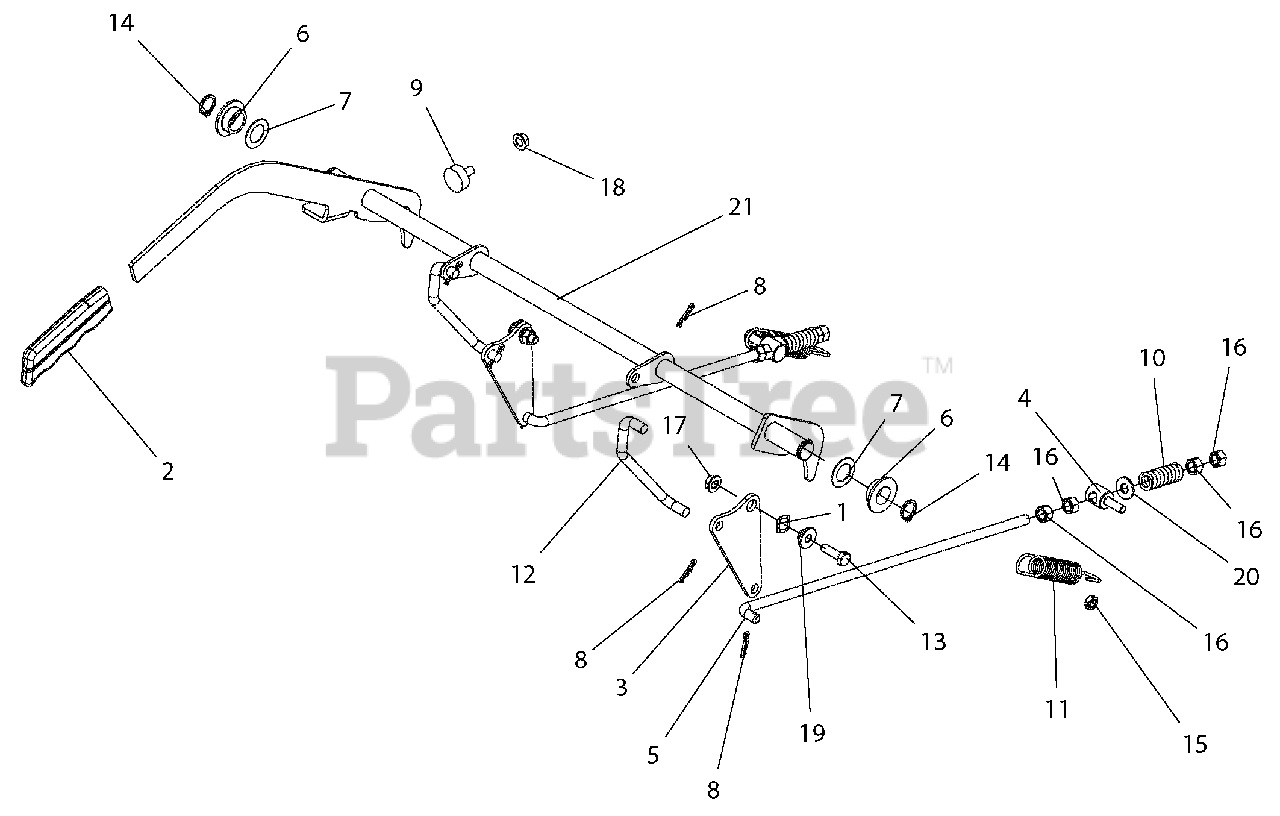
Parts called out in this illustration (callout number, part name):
1	WAVE WASHER .531X.781X.125 FH
2	GRIP, PARKING BRAKE (YELLOW)
3	PLATE, BRAKE PIVOT-BLACK
4	TRUNNION, .31-18
5	ROD, BRAKE ADJ.
6	BSHG, FLANGE .762 X 1.48 X .44 NYLON
7	WSHR-HDND-THRST
8	PIN-HAIR, ENDRIES #25 YWZC
9	BUMPER, RUBBER
10	SPRG, COMPRESSION
11	SPRG, EXTENSION
12	LINKAGE, BRAKE ACTUATING
13	BLT-HEX .31-18X1.00 GR5 YWZC
14	RG-RTNG-EXT .750x.078
15	@NUT-LK-CTR-JAM .31-18 YWZC
16	NUT-HEX .38-16 YWZC
17	NUT, LK-TOP-FLG .312-18 YWZC
18	@NUT-SPNLK-FLG .312-18 YWZC
19	BSHG, FLG .32X.500.344X.880
20	WSHR-FL-STL.38X.875X.083 YWZC
21	WLDMT, BRAKE INTERLOCK
